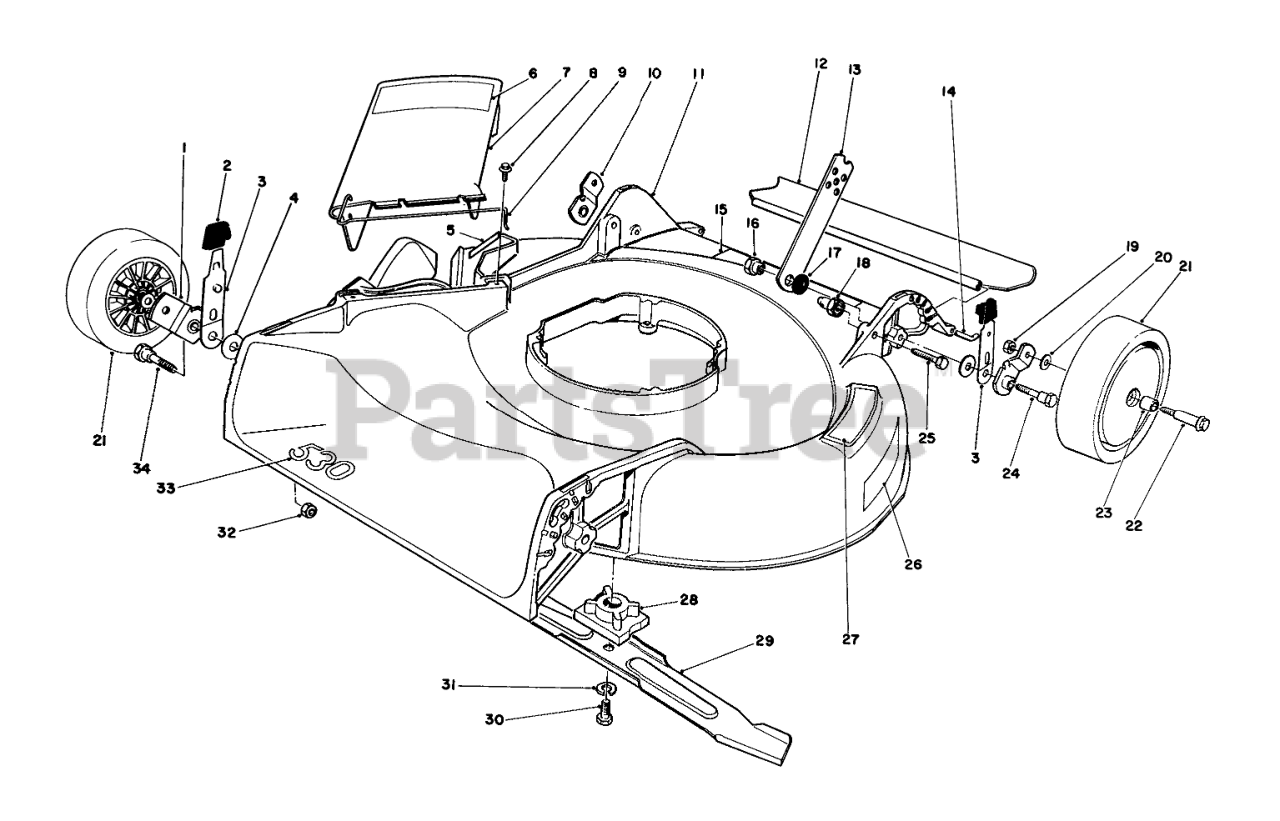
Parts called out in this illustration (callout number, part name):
1	Pivot Arm
2	KNOB-ARM
3	SPRING ARM ASM
4	WASHER-PIVOT
5	Decal-Danger
6	DANGER DECAL
7	Deflector Assembly (Incl. Ref. #6 & 9)
8	SCREW-HWH
9	SPRING HINGE
10	Pivot Arm
11	HOUSING/DECAL
12	REAR SAFETY SHIELD 21
13	HANDLE LATCH
14	SHIELD ROD
15	DECAL-DANGER
16	HANDLE PIVOT NUT
17	SPACER
18	HANDLE PIVOT NUT
19	NUT-LOCK
20	WASHER
21	Wheel & Tire Assembly (Incl. Ref. #23)
22	WHEEL BOLT
23	BUSHING
24	PIVOT SCREW
25	SCREW-HH
26	Decal-Place Foot Here
27	STEP PAD DECAL
28	BLADE RETAINER
29	Blade
30	SCREW-HH
31	WASHER-LOCK
32	NUT-LOCK, NI
33	Decal-530
34	PIVOT SCREW
